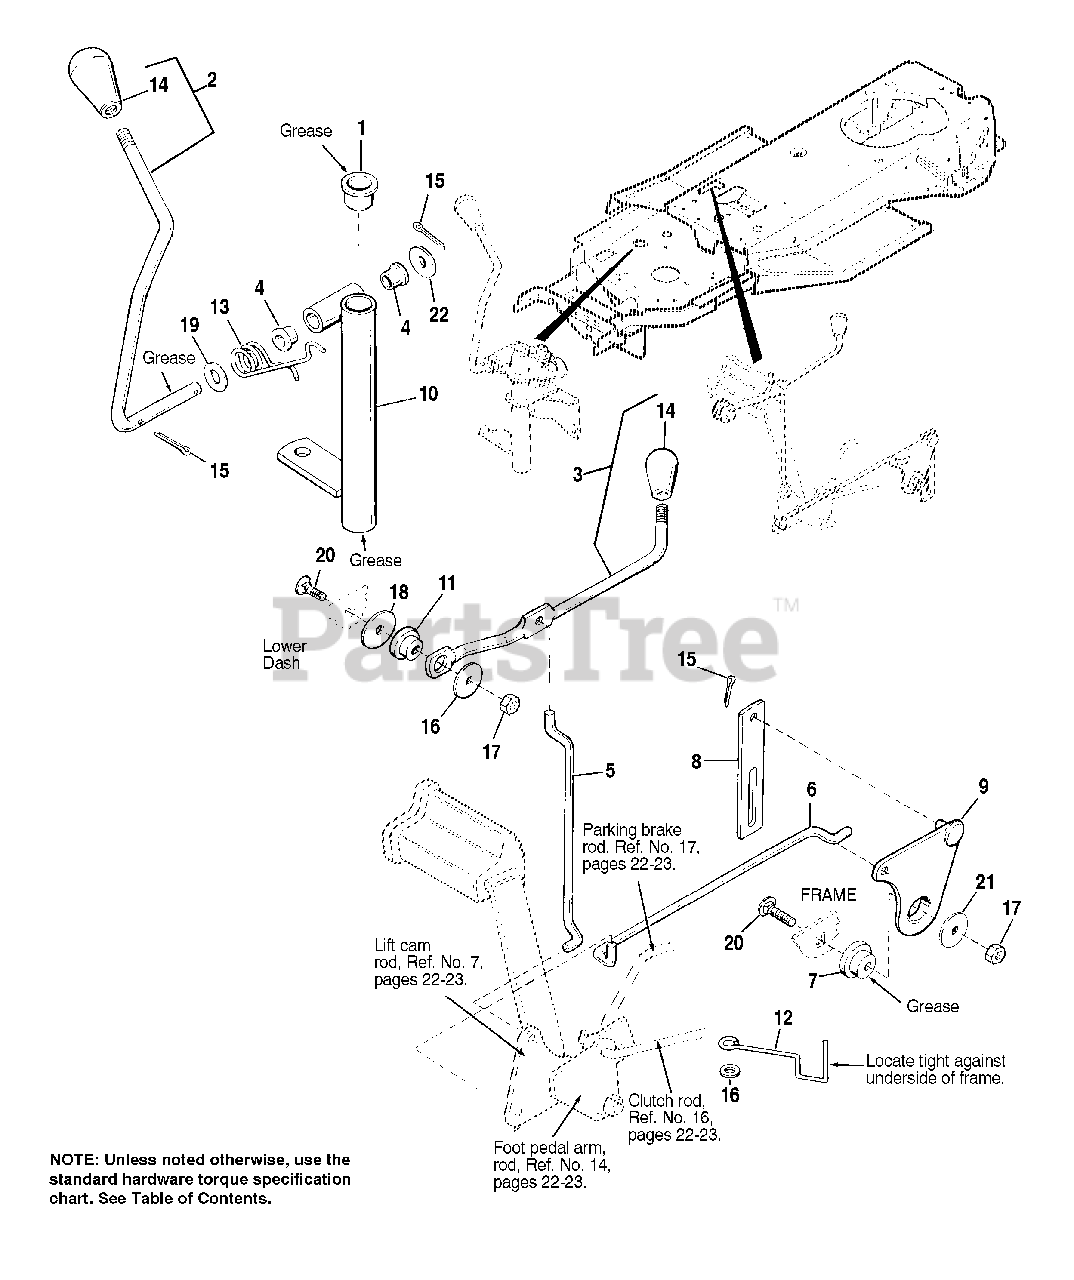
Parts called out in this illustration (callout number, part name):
1	BUSHING, Nylon
2	LEVER, Shift
3	ROD, Lift Handle
4	BUSHING, Plastic
5	LINK, Lift, Upper
7	SPACER
8	LINK, Lift, Upper Transport
9	CAM , Lift Assy.
10	SHIFT LEVER ASSY.
11	SPACER
12	BELT STOP
13	SPRING, Torsion
14	KNOB, Plastic
15	COTTER PIN, 3/32 x 3/4
16	WASHER, Plain, 5/16
17	NUT, Hex, ESNA, Lock, 5/16-18
18	WASHER, Plain, 13/32 x 1-1/5 x 1/8
19	WASHER, Plain, 17/32
20	CARRIAGE BOLT, 5/16-18 x 1-1/2
21	WASHER, Plain, 21/64 x 1-1/4 x 5/64
22	WASHER, Plain, 33/64
